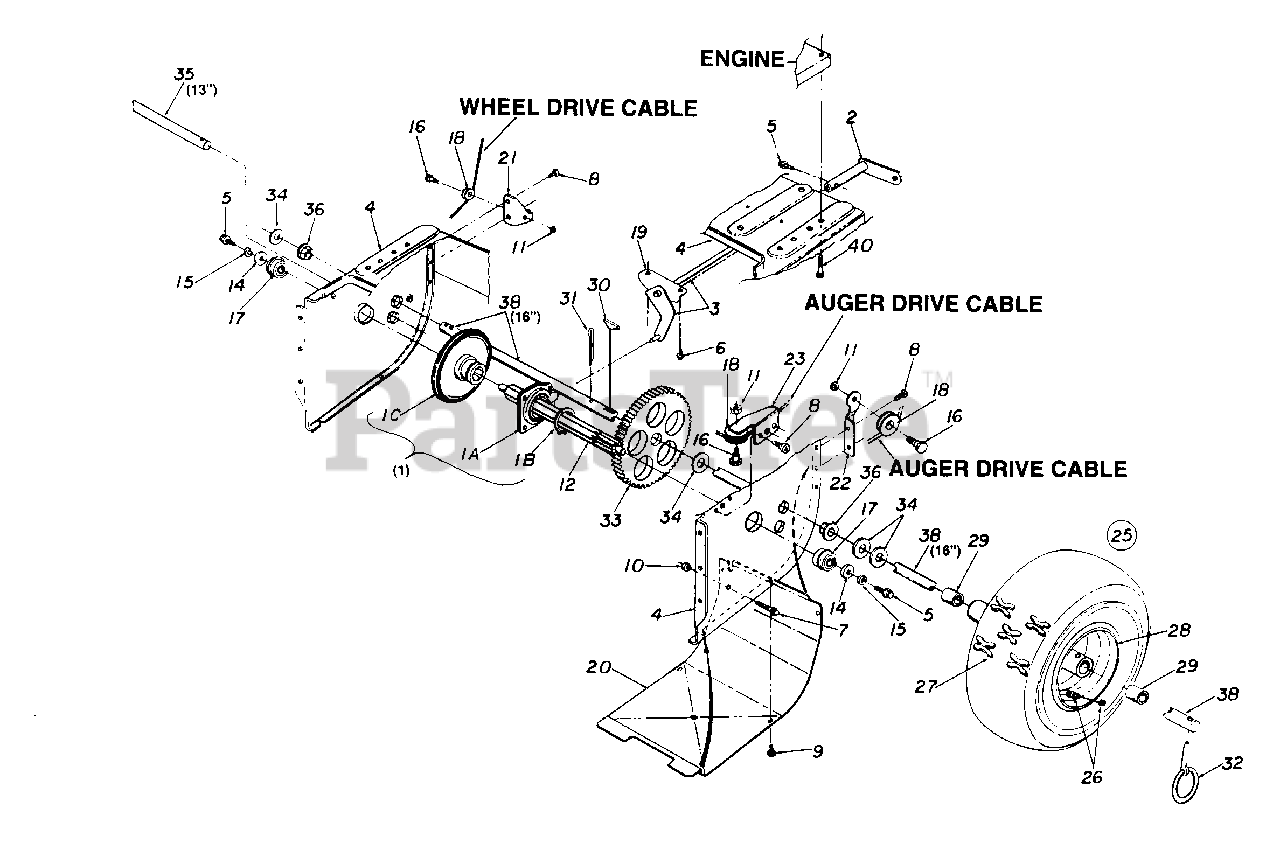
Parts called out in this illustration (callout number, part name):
1	Friction Wheel Ass'y. Comp.
1A	Friction Wheel Brg. Ass'y.
1B	Retaining Ring
1C	Friction Wheel
3	Shift Rod Ass'y.
6	Hex Tap Scr. 1/4-20 x .38" Lg.
7	Hex Wash. Hd. TT-Tap Scr. 1/4-20 x 1" Lg.
8	Torx Mach. AB-Tap Scr. 1/4 x .62" Lg.
9	Hex Wash. Tap Scr. #12 x .38" Lg.
10	Hex Nut 1/4-20 Thd.
11	Hex Jam Nut 1/4-20 Thd.
12	Gear Shaft
14	Fl-Wash. .265" I.D. x .938" O.D.
15	L-Wash. 1/4" I.D.
16	Shld. Bolt 5/16 Dia. x .35" Lg.
17	Ball Brg. w/Snap Ring
18	Cable Roller Guide
30	#9 Hi-Pro Key 3/16" x 3/4" Dia.
31	Cotter Pin 3/16" x 1.5" Lg.
32	Klik Pin
33	79 Tooth Gear
34	Fl-Wash. .76" I.D. x 1.49" O.D.
35	Wheel Axle
36	Hex Flange Brg. .752" I.D.
38	Wheel Axle
40	Hex Bolt 3/8-16 x 1.25"
